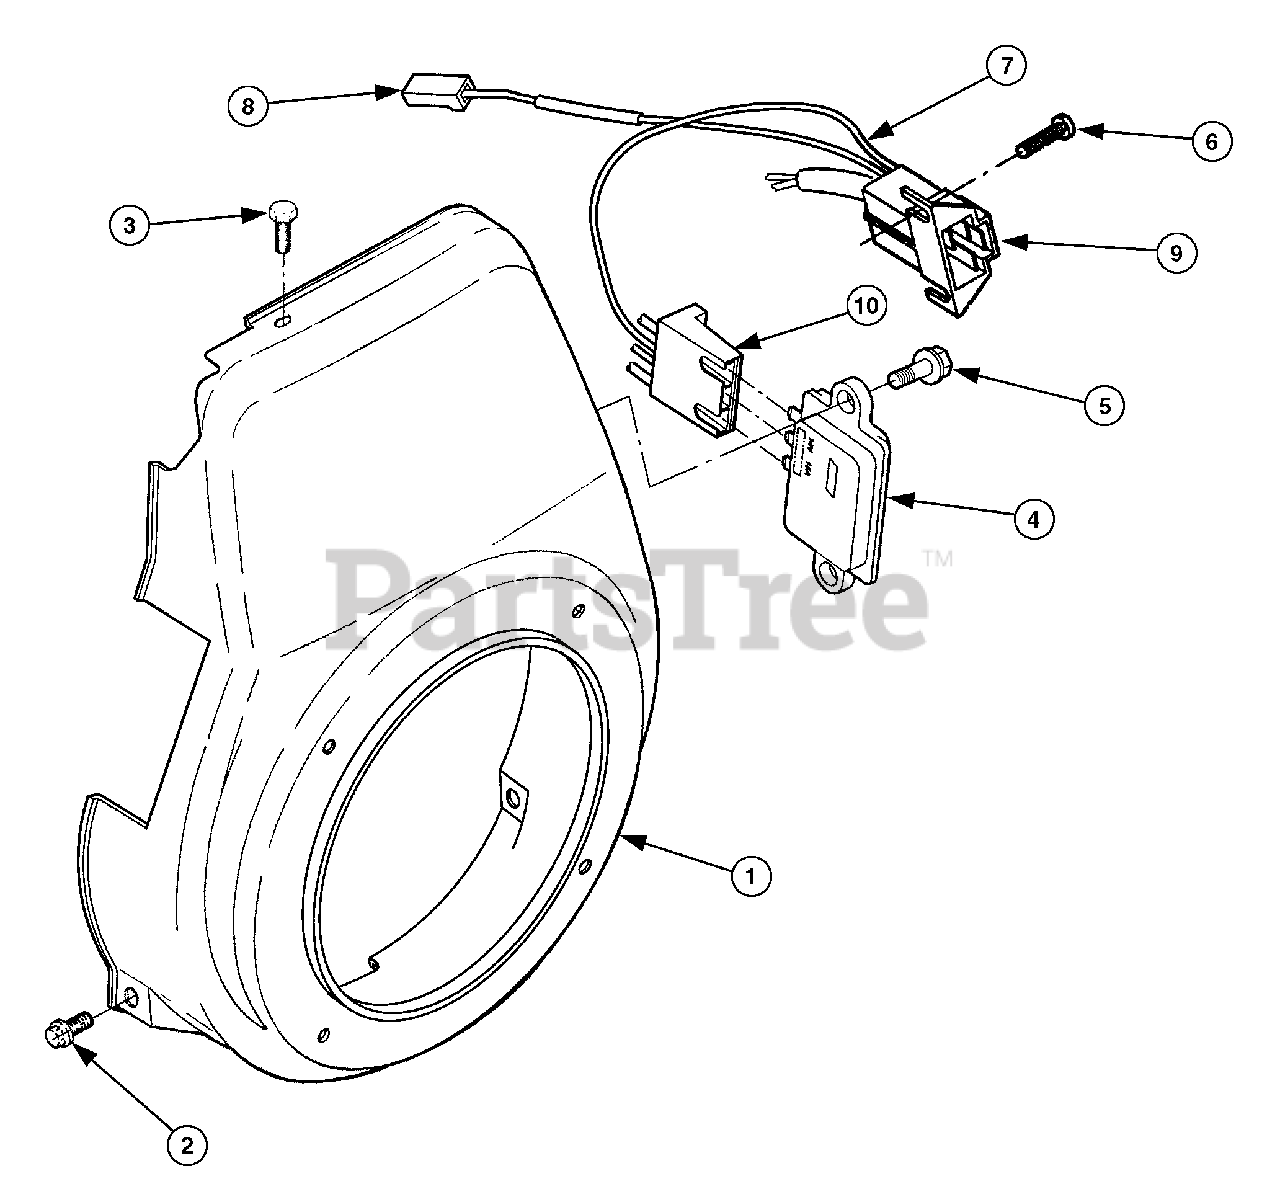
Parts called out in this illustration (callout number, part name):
1	Housing, BLower
2	Screw, Hex Washer Lock, M6 x 1 x 16
3	Bolt, Hex Hd Cap, M6 x 14
4	Regulator, Voltage (VR1)
5	Screw, Hx Hd Sheet Metal, 1/4-14 x .5
6	Screw, Pan Hd Torx, M4 x .7 x 12
7	Harness, Engine
8	Housing, Receptacle
10	Body, Connector
